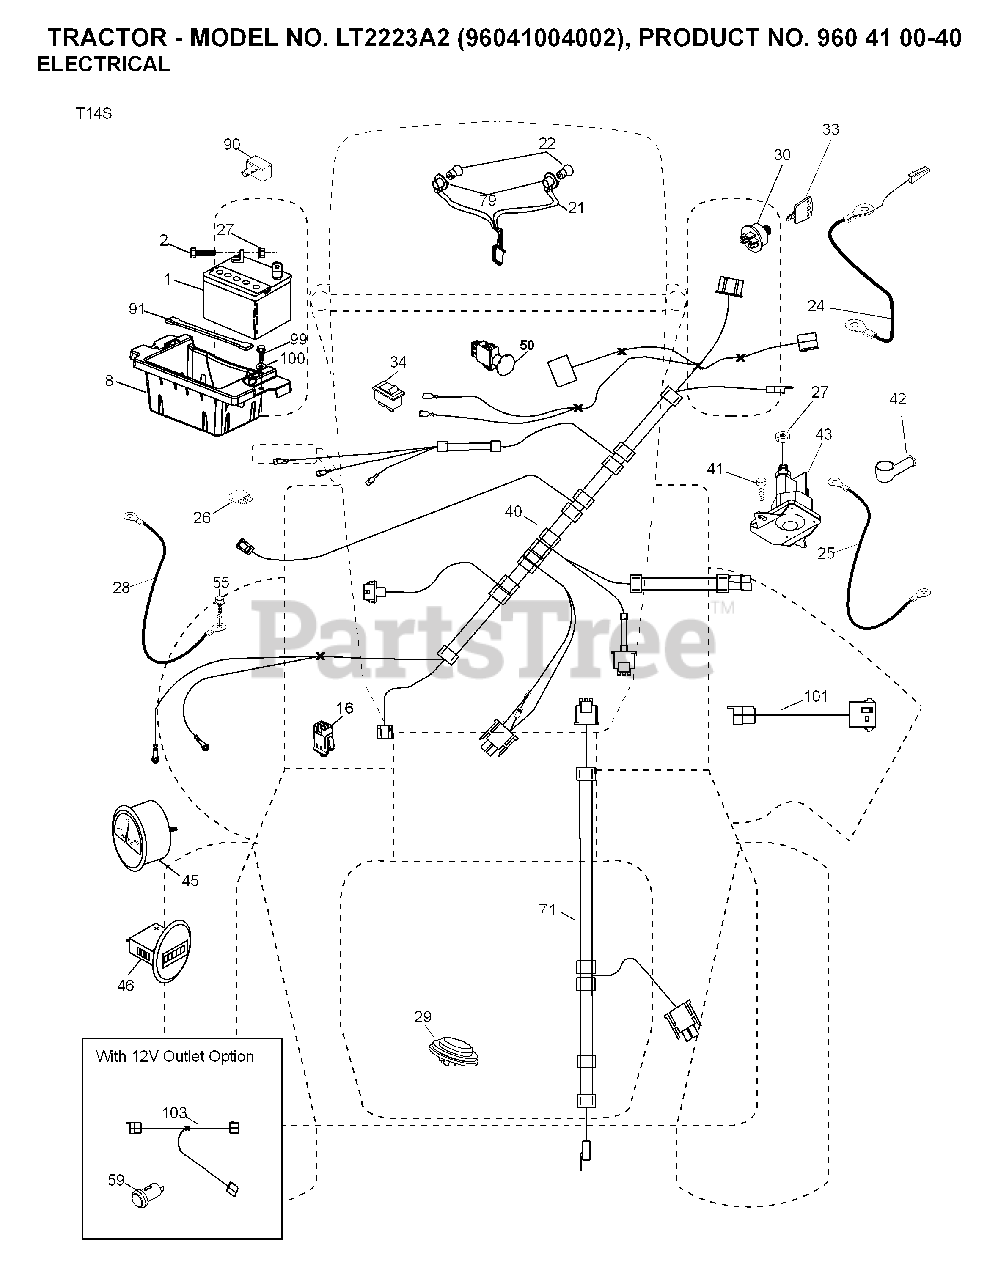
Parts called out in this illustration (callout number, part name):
1	BATTERY 12V .35 AMP
8	BOX.BATTERY.MOUNT.FRONT.LT
16	SWITCH INTERLOOK PUSH-IN
21	HARNESS.W/LIGHT SOCKET
22	LIGHTBULB
24	CABLE.BATT.POS.WIRE.TG.DA SOL
25	CABLE.START.RED.17.5".
26	FUSE 20AMP
27	NUT
28	CABLE GROUND 6 GA 21" 90T BLK
29	SWITCH.SEAT.DELTA.OPC.
30	SWITCH.IGN.DELTA.W.LGH.ROS
33	KEY.CHAIN.BLISTER.PACK.GEN.USA
34	SWITCH LT
40	HARNESS.IGN.ELE.RELAY.TEX.46"
41	SCREW
42	TERMINAL COVER
43	SOLENOID.W/BRASS.PLUNG
46	GUAGE.SRVCMNDR.HRMTR.
50	PTO SWITCH
55	SCREW 5/16"
71	HARNESS-CHASSIS SUB
79	BULB HOLDER ASM.
90	COVER.TERMINAL.BATTERY
91	STRAP, BATTERY MOUNT
99	SCREW HEXWSHR 1/4-20X3/4
101	PIGTAIL.MATNLK.NEW.HAR
102	HARNESS PIGTAIL PCH TEX ROS
104	RELAY HARNESS.SEALED
105	REVERSE SWITCH
